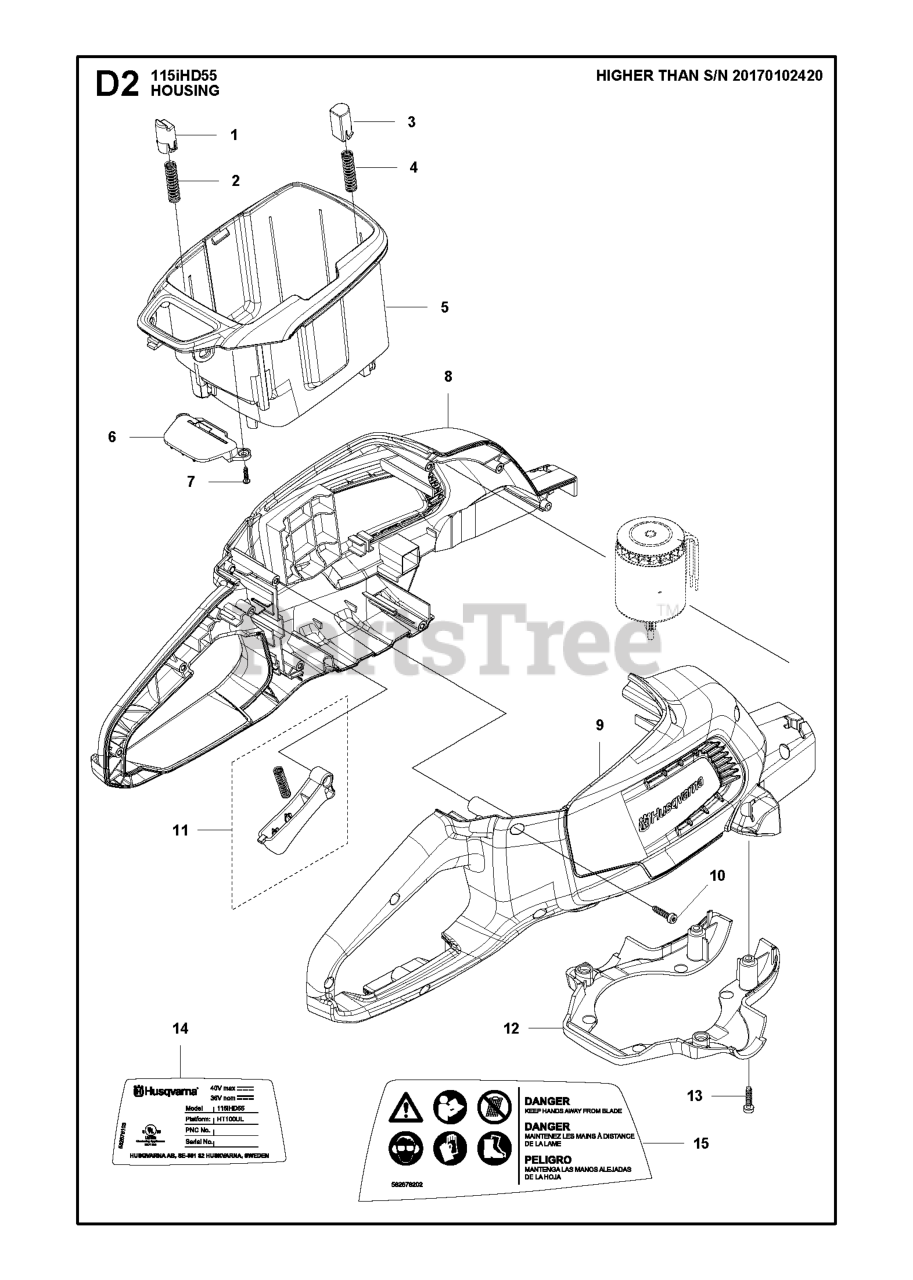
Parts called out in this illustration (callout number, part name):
1	PUSH BUTTON
2	SPRING PUSH BUTTON
3	PUSH BUTTON FRONT
4	SPRING PUSH BUTTON
5	BATTERY BOX
6	BRACKET KEYPAD
7	SCREW ST3X8
8	HOUSING LEFT - HOT FOIL+PAINTI
10	SCREW ST4X16
12	COVER BOTTOM
13	SCREW ST4X16
14	DECAL RATING DECAL 115IHD55 HE
15	DECAL WARNING DECAL 115IHD55 H
